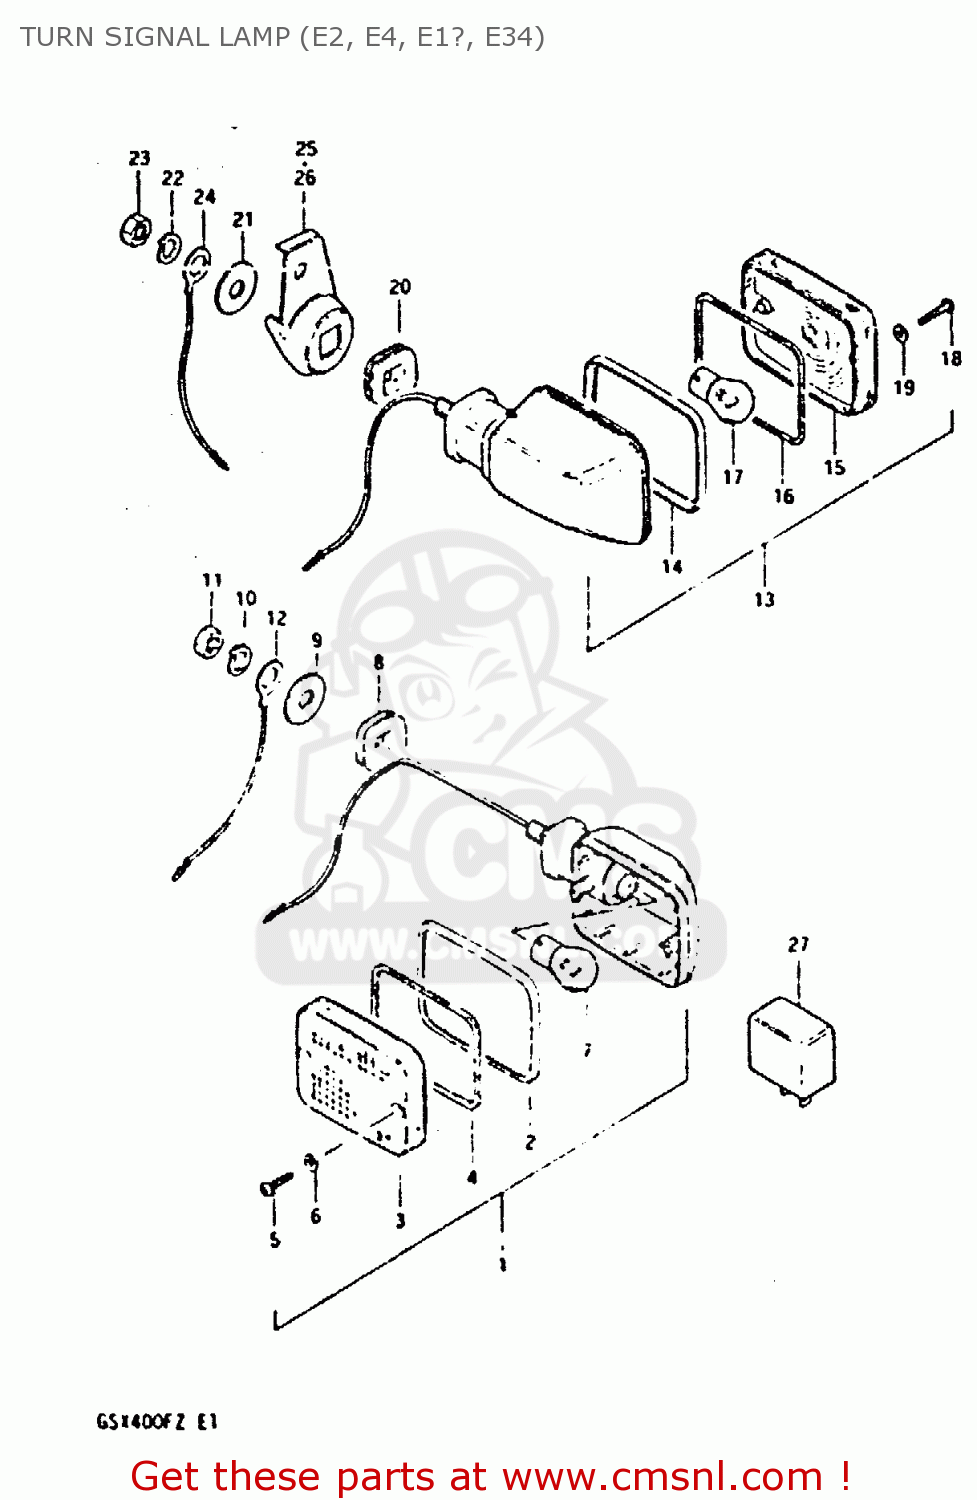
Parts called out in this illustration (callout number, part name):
1	LAMP ASSY,FR T
2	RIM
3	LENS
4	GASKET (NAS)
5	SCREW
6	GASKET (NAS)
7	BULB(12V21W)
8	CUSHION
9	WASHER (10.5X30X2.3)
10	LOCK WASHER
11	NUT
12	LEAD WIRE,EARTH
13	LAMP, REAR TURN SIGNAL
14	RIM
16	GASKET (NAS)
17	BULB(12V21W)
18	SCREW
19	GASKET (NAS)
20	CUSHION
21	WASHER (10.5X30X2.3)
22	LOCK WASHER
23	NUT
24	LEAD WIRE,EARTH
25	BRACKET,REAR TURN SIGNAL
26	BRACKET,REAR TURN SIGNAL
27	RELAY,TURN SIGNAL
